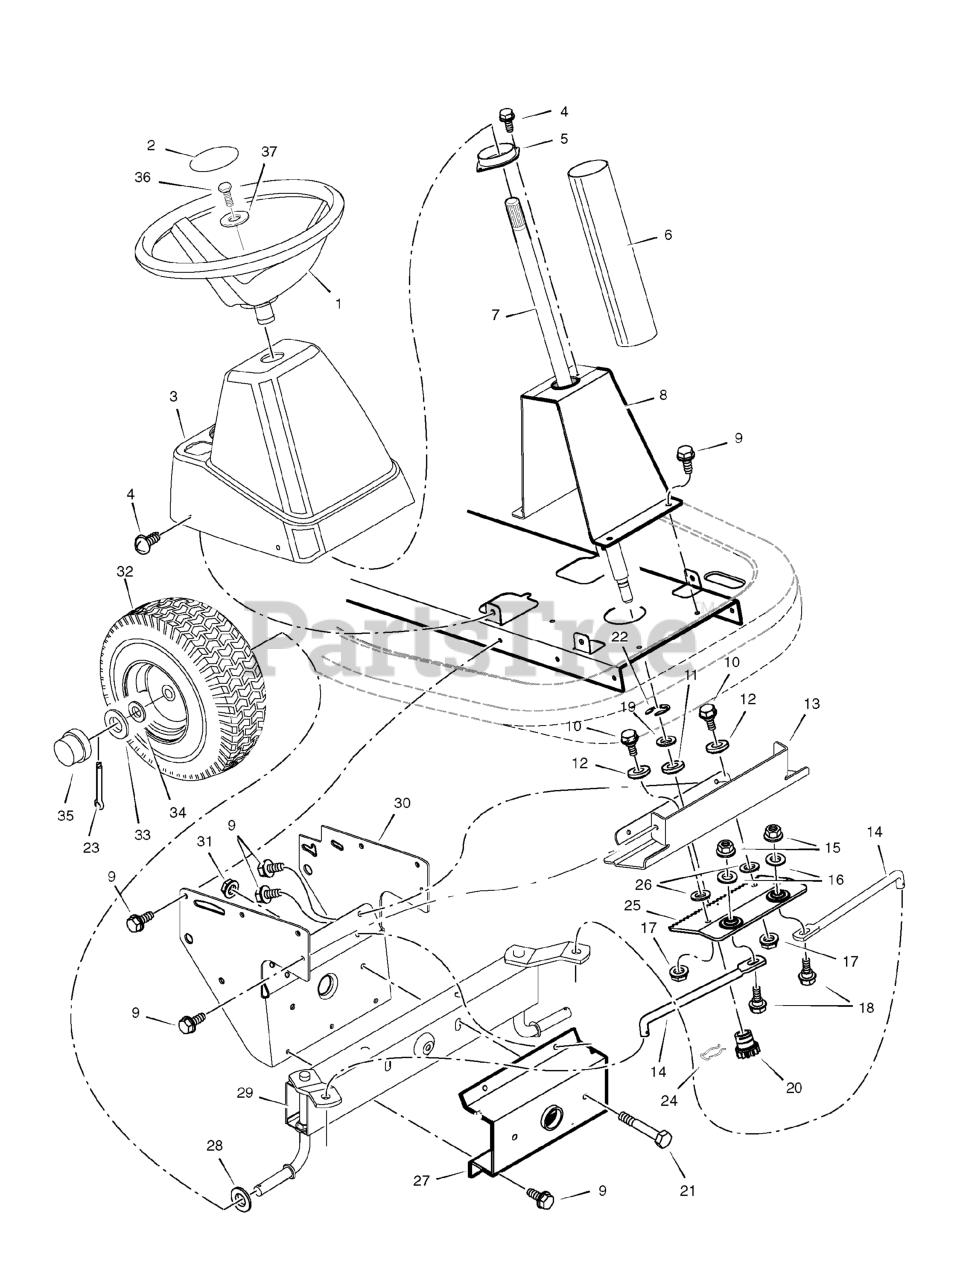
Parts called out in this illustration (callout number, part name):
1	Wheel, Steering
2	Insert, Steering
3	Console, Low (Gray)
5	Bearing, Upper Steering
6	Tube, Steering
7	Shaft, Steering
8	Support, Steering
10	Bolt, Shoulder
11	Bearing, Lower Steering
13	Plate, Gear Mounting
15	Nut, Flange
16	Washer
17	Nut, Flange
18	Bolt, Hex
20	Gear, Pinion
21	Bolt, Hex
22	E-Ring, Retainer
23	Pin, Cotter
24	Retainer, Spring
25	Rack, Steering
27	Bracket, Axle Front
29	Axle & Spindle Assembly
30	Bracket, Support
31	Nut, Flange
32	Wheel Assembly, Front
35	Cap, Hub
36	Screw, Hex
37	Washer
